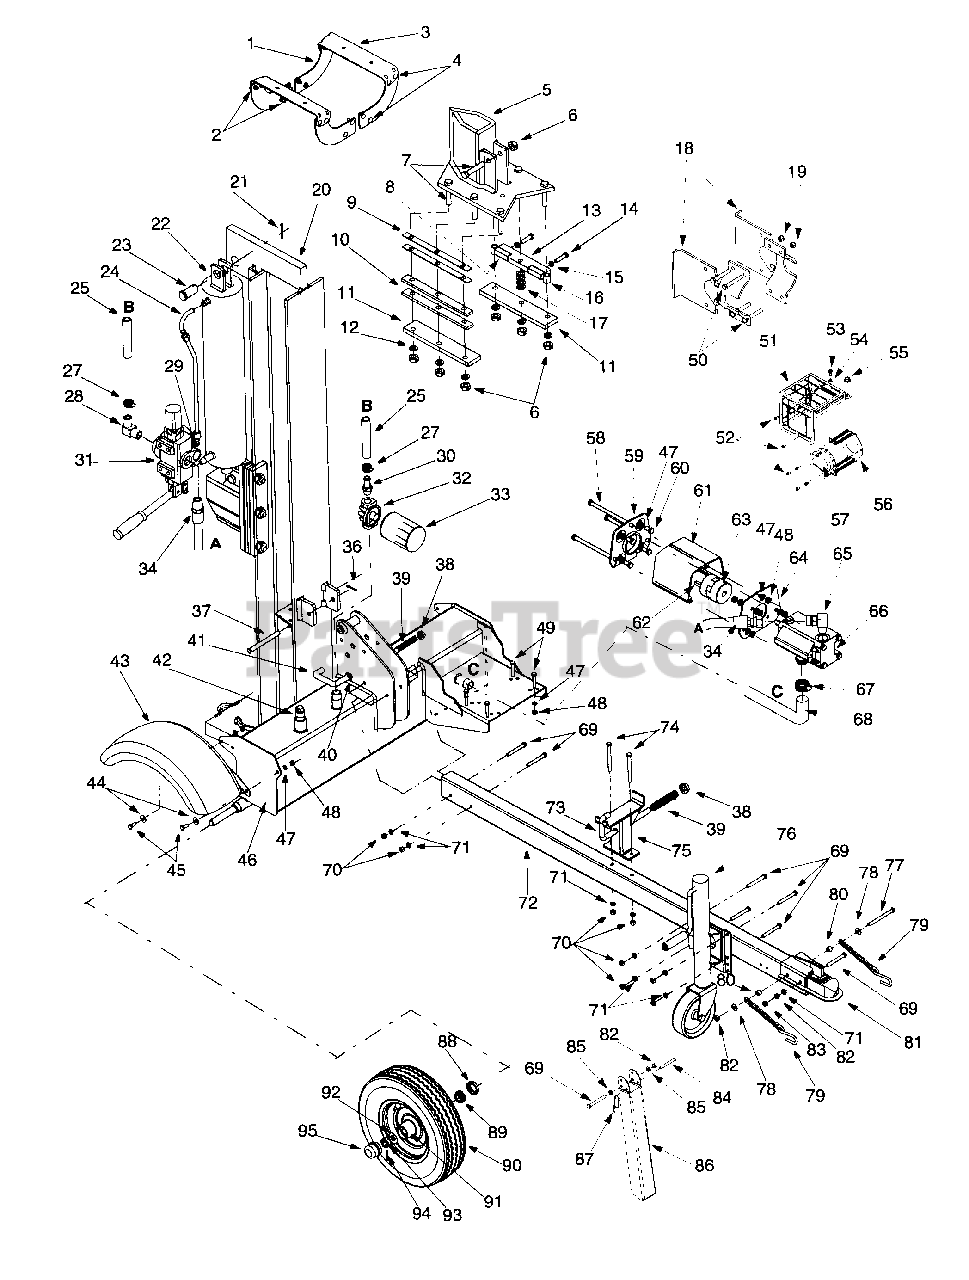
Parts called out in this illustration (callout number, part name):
4	Carriage Bolt 3/8-16 x 1.0
6	Lock Nut 1/2-20
7	Hex Cap Screw 3/2-20 x 2.75
12	Lock Washer 1/2
14	Hex Cap Screw 3/8-24 x 1.5
15	Hex Jam Nut 3/8-24
16	Spacer
17	Flat Washer .531 x .93 x .090
24	Hydraulic Tube
25	Return Hose 3/4" ID x 44" Lg
27	Hose Clamp 5/8"
28	Return Elbow
29	90 Degree Solid Male Adapter
30	3/4" Hose Adapter
32	Filter Housing
33	Oil Filter
34	High Pressure Hydraulic Hose
36	Cotter Pin 1/8" Dia
37	Hinge Pin 1/2 x 4.8" Lg.
38	Push Cap
39	Comp. Spring 4" Lg.
40	Flat Washer .635 ID x .93 OD
41	Locking Rod
42	Pipe Plug
45	Hex Cap Screw 5/16-24 x .75
48	Hex Nut 5/16-24
49	Hex Cap Screw 5/16-24 x 1.75
50	Hex Cap Screw 3/8-16 x 2.5
51	Muffler Guard
52	Hex Washer Screw
53	Screw 1/4-20 x .50
54	Lock Washer 1/4
55	Lock Nut 5/16-18
56	Muffler Guard Bracket
57	Muffler Deflector
58	Hex Screw 5/16-24 x 4.0
60	Hex Cap Screw 5/16-24
61	Coupling Shield
63	Flex Coupling
65	Adapter
66	Gear Pump (11 gpm)
67	Hose Clamp
68	Suction Hose
69	Hex Cap Screw 3/8-16 x 3.0
70	Hex Nut 3/8-16
71	Lock Washer 3/8
73	Locking Rod
74	Hex Cap Screw 3/8-16 x 4.0
77	Hex Cap Screw 3/8-16 x 4.25
78	Flat Washer .385 ID x .870 OD
79	Chain
80	Spacer
81	Hitch Coupler
82	Lock Nut 3/8-16
83	Hex Jam Nut 3/8-16
84	Clevis Pin
85	Flat Washer
88	Bearing Seal Only
89	Bearing Cone
90	Wheel Asm Comp - Gray
91	Bearing Cup
92	Flat Washer .76" ID x 1.5" OD
93	Slotted Nut 3/4-16
94	Cotter Pin 5/32" x 1-1/4" Lg.
95	Hub Cap
